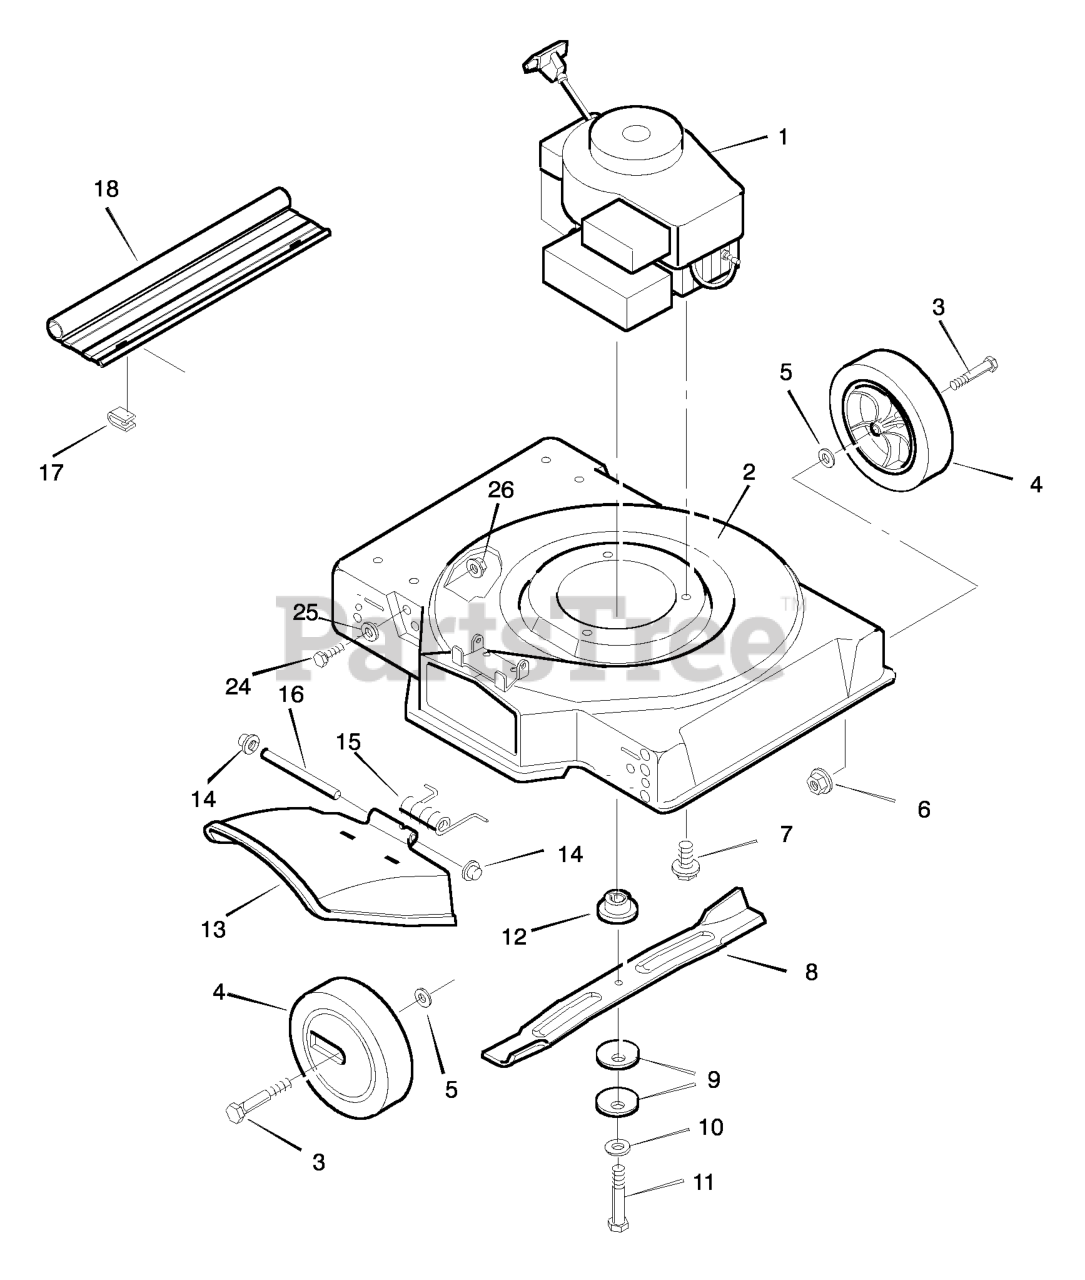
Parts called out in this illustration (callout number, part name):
1	Engine
2	Housing
3	Bolt, Axle
4	Wheel and Tire
6	Locknut, Flange
7	Bolt, Engine
9	Washer, Belleville
11	Bolt, Hex
12	Adapter, Blade
13	Deflector, Chute
14	Push- On Cap
16	Pin, Pivot
17	Retainer
18	Guard, Rear
24	Bolt, Hex
26	Locknut, Flange
